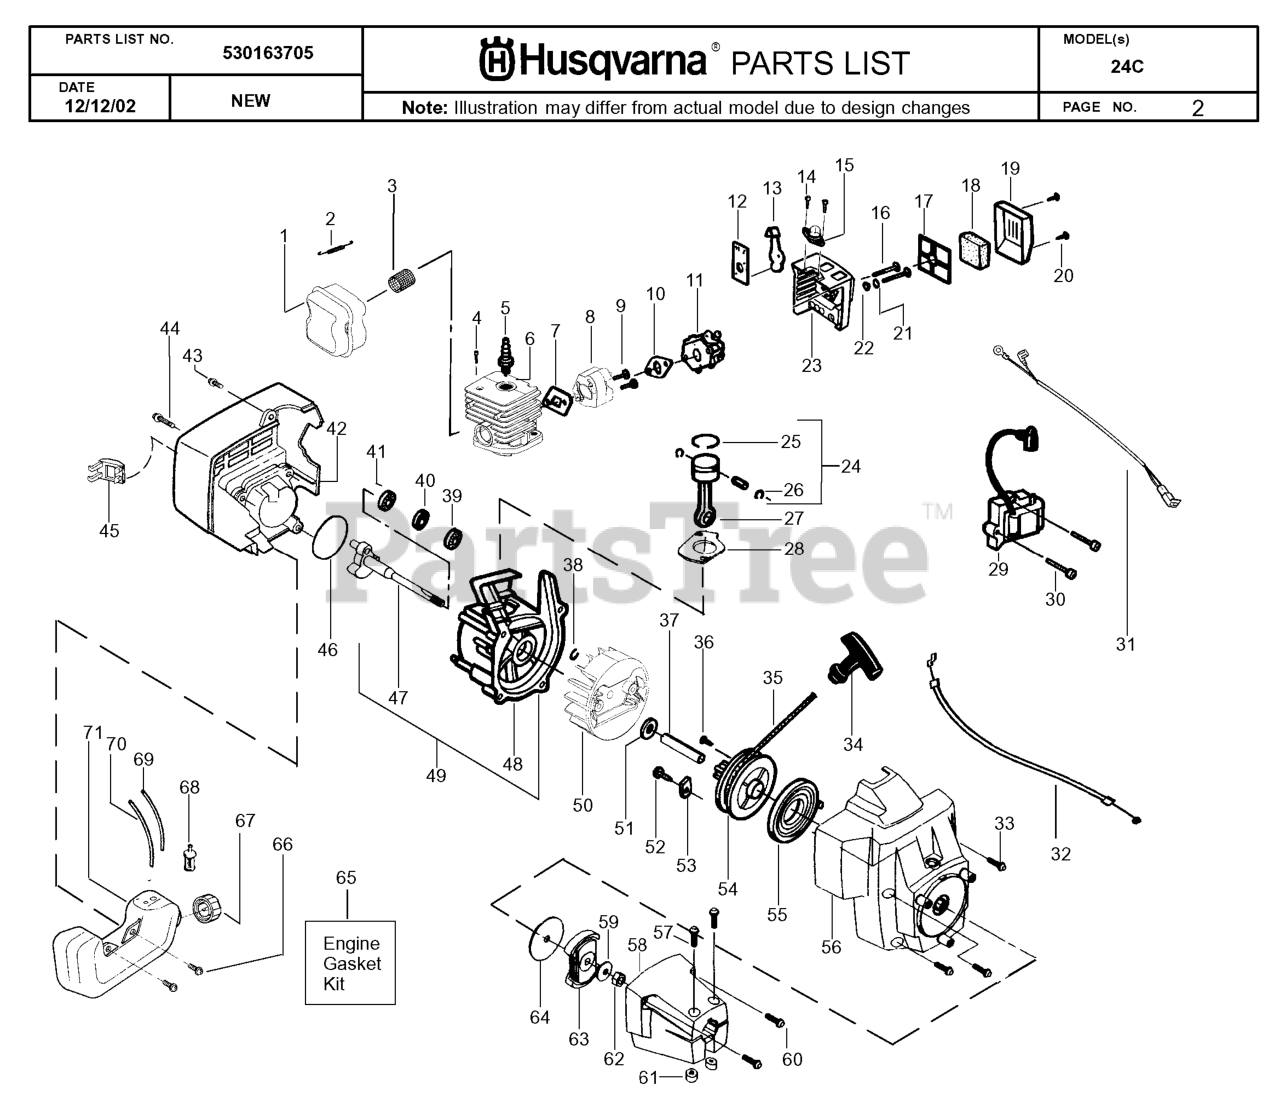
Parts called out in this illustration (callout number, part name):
1	KIT-MUFFLER
2	SPRING-MUFFLER (NEW STYLE)
6	KIT CYLINDER
7	GASKET KIT
8	ASSY CARB ADAPTOR PHENOLRE
9	SCREW - CARB. ADAPTOR
10	GASKET KIT
11	CARBURETOR
12	CHOKE PLATE
13	CHOKE SHUTTER
14	SCREW 6-19X5/8 PLAS.PAN
15	AIR PURGE BUBBLE
17	FILTER PLATE
18	AIR FILTER FOAM
19	AIR FILTER COVER
20	SCREW FILTER PLATE
21	CHOKE SPACER
23	FILTER HOLDER
24	PISTON
25	PISTON RING
26	WRIST PIN RET.
27	KIT-CONN ROD ASSY
28	GASKET KIT
29	IGNITION MODULE
31	LEAD WIRE ASSEMBLY
32	THROTTLE WIRE
33	SCREW - SHROUD
34	STARTER HANDLE
38	RETAINING RING
39	OUTER BEARING
40	KIT-CRANKCASE SEAL
42	SHROUD HUSQ ORANGE
44	SCREW - SHROUD
46	GASKET KIT
47	ASSY-CRANKSHAFT
48	KIT ASSY CRANKCASE
49	KIT ASSY C'CASE/C'SHAFT
50	FLYWHEEL
52	SCREW 8-16 X 9/16 (PLAS
54	STARTER PULLEY KIT
55	STARTER SPRING
57	SCREW-10-24 X 1-3/8 (UN
58	ASSY CLUTCH HSG HUSKY
59	WASHER FLAT
60	SCREW-10-14 X 13/16 (PL
61	LOCKNUT-HEX 10-24
63	CLUTCH ASSEMBLY KIT
64	FRICTION DISC,CLUTCH 36/41
65	GASKET KIT
68	FUEL PICK-UP ASSY
69	KIT.LINE TANK/PURGE
70	HOSE. FUEL
